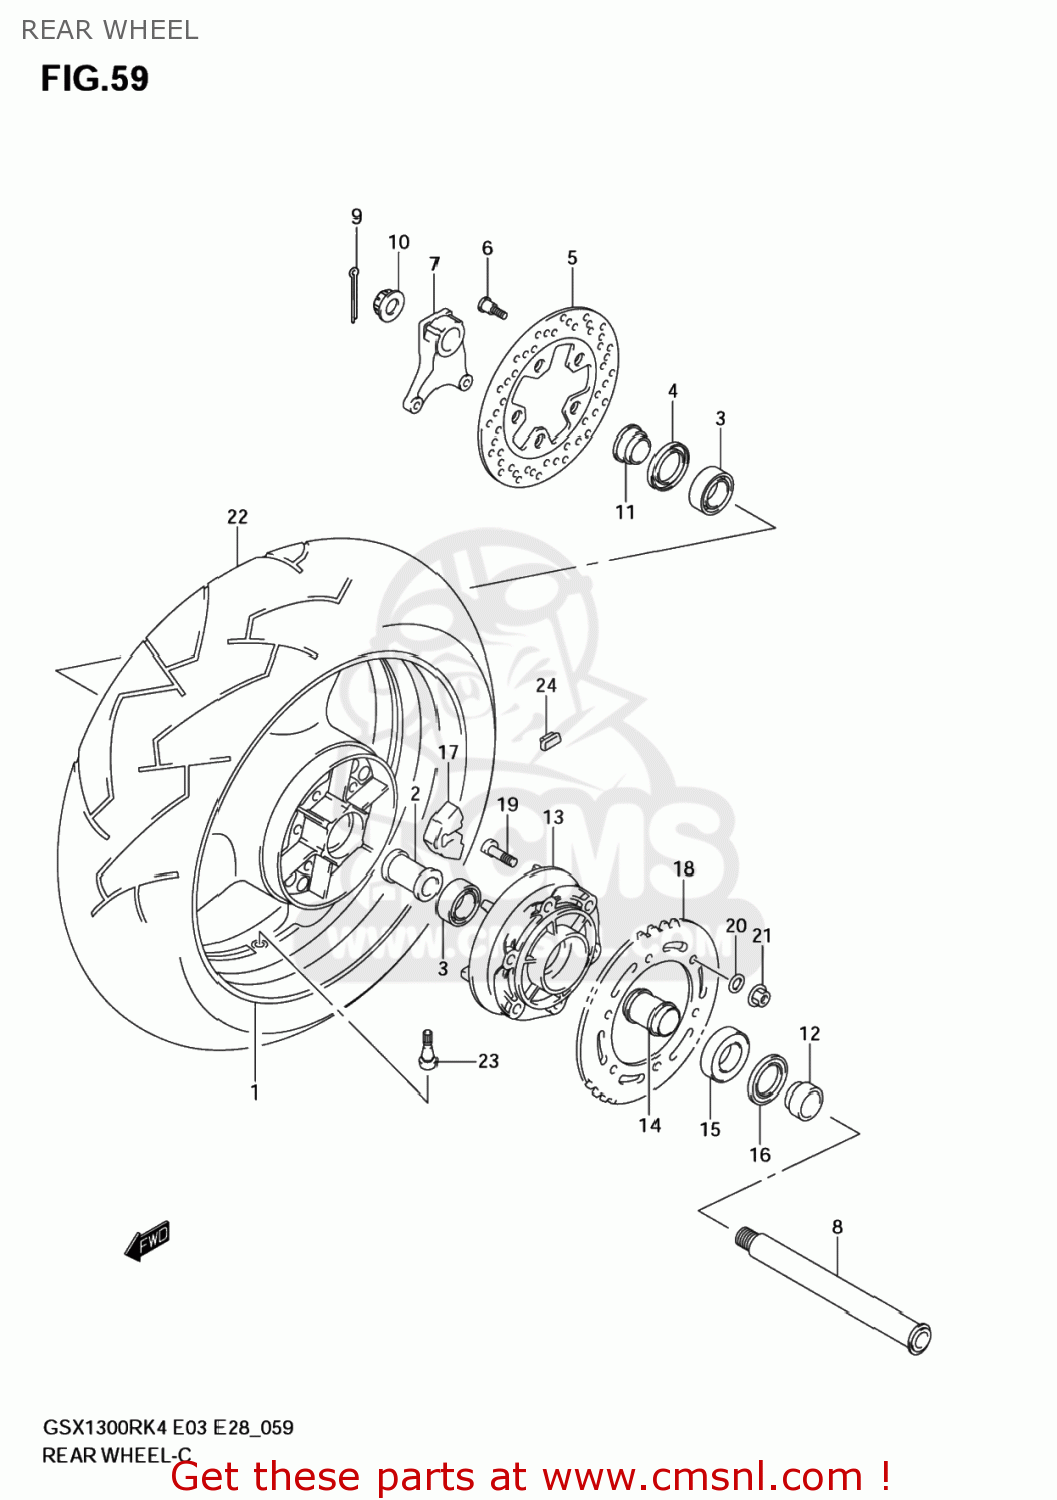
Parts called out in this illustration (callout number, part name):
1	WHEEL,RR(17M/CXMT6.00)
2	SPACER,RR HUB BEARING
3	BEARING(32X58X13)
4	SEAL,OIL(38X58X7)
5	DISC,RR BRAKE
6	BOLT(8X33)
7	BRACKET,RR CALIPER
8	AXLE,RR
9	PIN
10	NUT
11	SPACER,RR AXLE,R
12	SPACER,RR AXLE,L
13	DRUM,RR SPROCKET
14	RETAINER,RR SPROCKET DRUM
15	BEARING
16	SEAL,OIL(39X65X7)
17	ABSORBER,RR HUB SHOCK
18	SPROCKET,RR(NT:40-530)
19	BOLT
20	WASHER
21	NUT
22	TIRE,RR(190/50 ER17 73W)
23	VALVE ASSY,WHEEL RIM(TR412)
24	BALANCER,WHEEL(10G)
